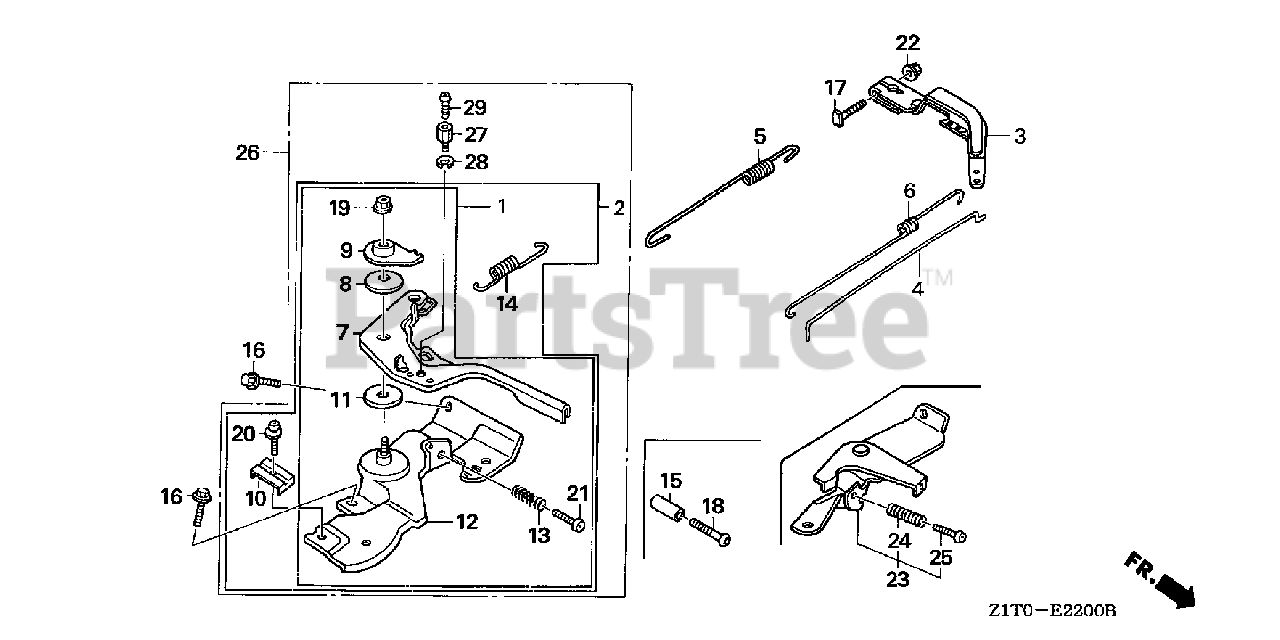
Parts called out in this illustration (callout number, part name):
2	CONTROL ASSY. (REMOTE)
3	ARM, GOVERNOR
4	ROD, GOVERNOR
5	SPRING, GOVERNOR
6	SPRING, THROTTLE RETURN
7	LEVER, CONTROL
8	SPRING, LEVER
9	WASHER, CONTROL LEVER
10	HOLDER, CABLE
11	SPACER, CONTROL LEVER
12	BASE, CONTROL (REMOTE)
13	SPRING, CONTROL ADJUSTING
14	SPRING, CABLE RETURN
16	BOLT, FLANGE (6X12) (CT200)
17	BOLT, GOVERNOR ARM
19	NUT, SELF-LOCK (6MM)
20	SCREW, PAN (5X16)
21	SCREW, PAN (5X25)
22	NUT, FLANGE (6MM)
